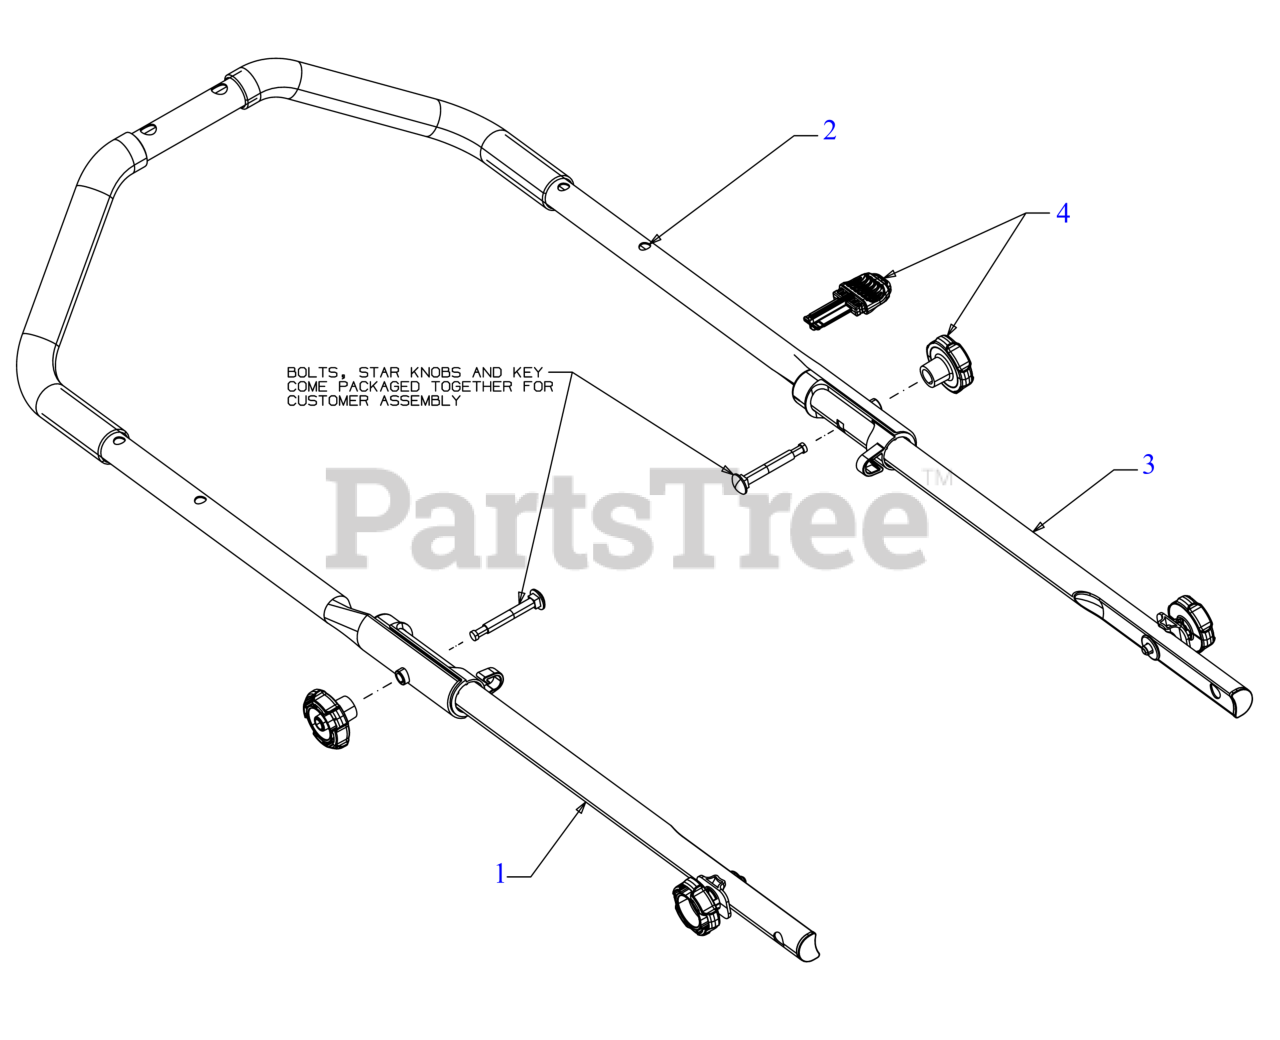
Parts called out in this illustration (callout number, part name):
1	HANDLE (LOWER)
2	HANDLE (UPPER)
3	HANDLE (LOWER)
4	HARDWARE KIT (KNOB/KEY) (BLACK)
